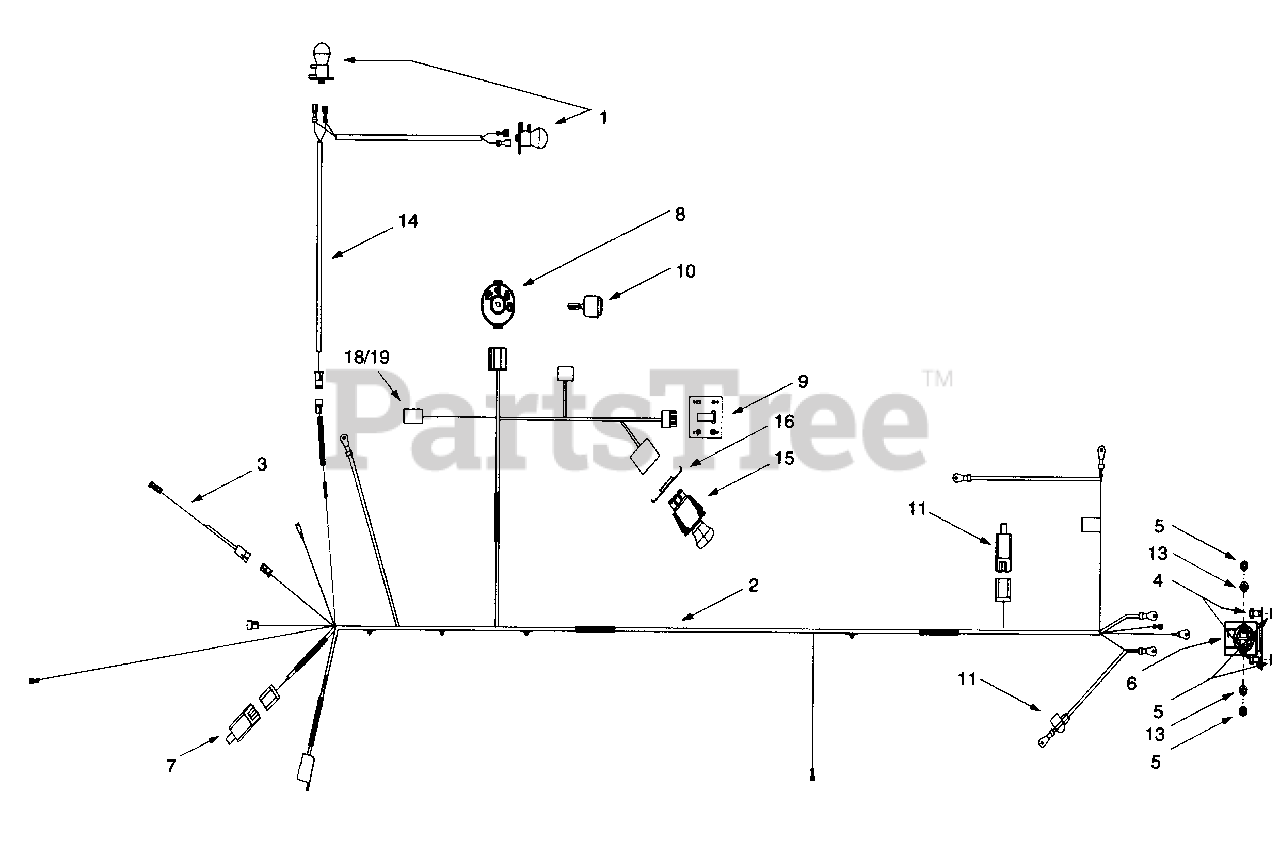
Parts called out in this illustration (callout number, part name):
1	Bulb/Socket Headlight Assembly
2	Wiring Harness w/o Ref. 14
3	Harness Adapter, #18 x 5
4	Self-Tapping Screw,1/4-20x.5
5	Hex Nut, 1/4-20
6	Solenoid, 12-volt, 100 Amp
7	Snap Mount Safety Interlock Switch (Brake)
8	Ignition Switch
9	Indicator Monitor / Hour Meter
10	Ignition Key
11	Safety Plunger Switch (Seat)
13	Lock Washer, 1/4
14	Headlight Harness
15	Electric PTO Switch
16	Retainer Bracket
18	Fuse Holder
19	20-amp Fuse
